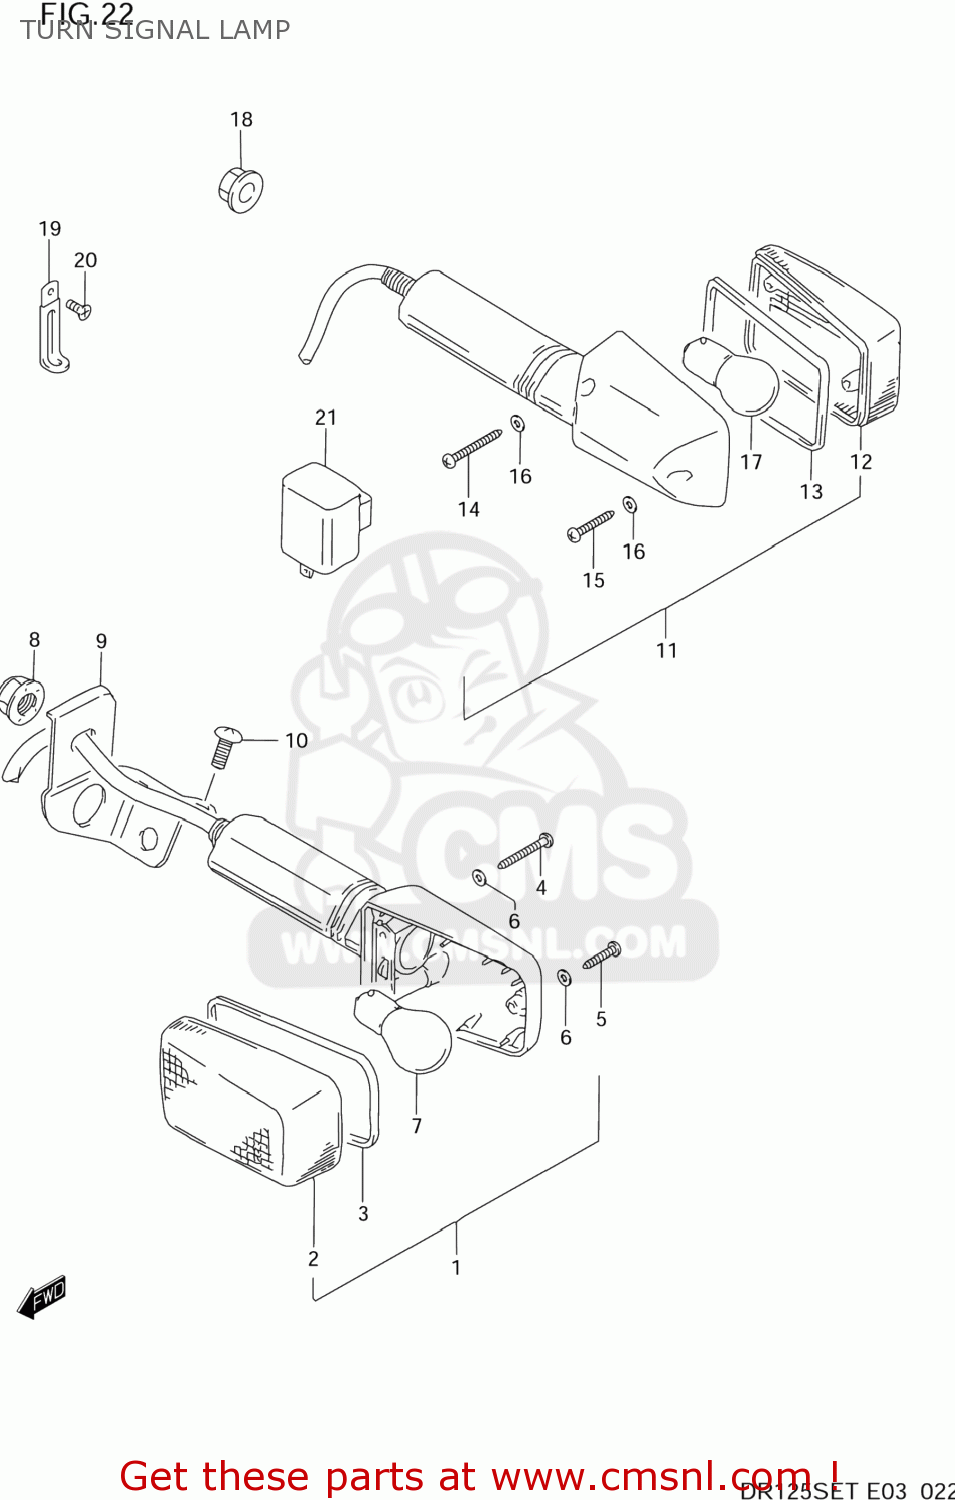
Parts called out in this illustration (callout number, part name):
1	LAMP ASSY,FR TURN SIGNAL
2	LENS
3	GASKET (NAS)
4	SCREW(3X30)
5	SCREW
6	GASKET (NAS)
7	BULB(12V21W)
8	NUT
9	BRACKET,FR TURN,R
10	SCREW
11	LAMP ASSY,RR TURNSIGNAL
12	LENS
13	GASKET (NAS)
14	SCREW(3X30)
15	SCREW
16	GASKET (NAS)
17	BULB(12V21W)
18	NUT
19	CLAMP(L:45)
20	SCREW
21	RELAY ASSY,TURNSIGNAL
